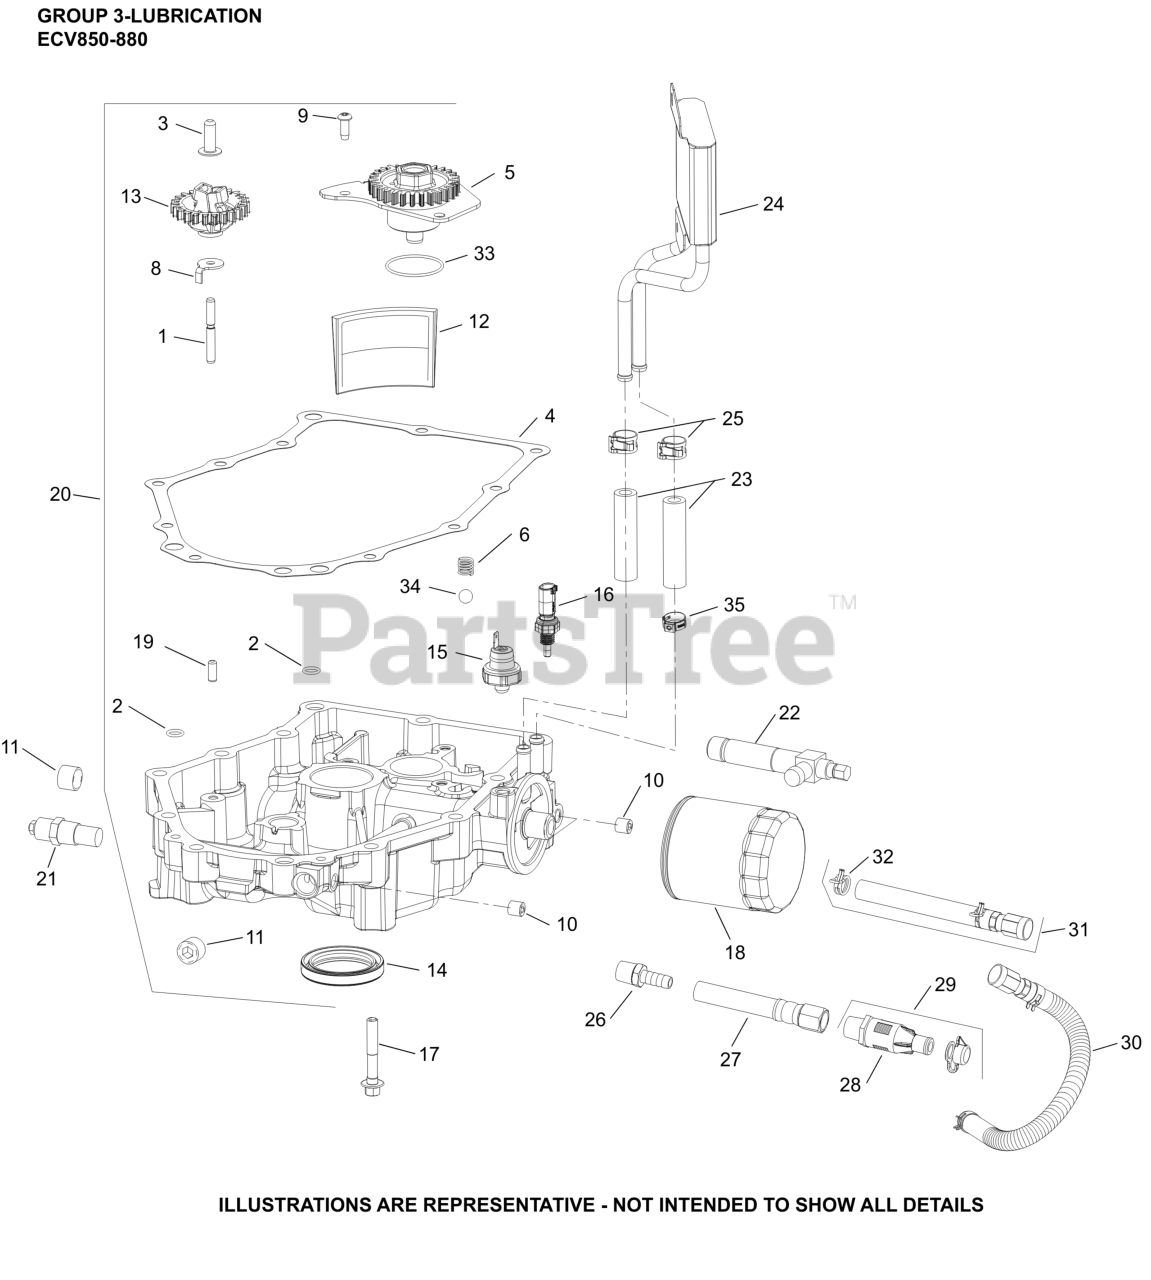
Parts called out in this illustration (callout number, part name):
1	SHAFT, GOVERNOR GEAR
2	O-RING (.5" DIA)
3	PIN, GOVERNOR REGULATING
4	GASKET, OIL PAN
5	PUMP ASSEMBLY, OIL
6	SPRING, COMPRESSION
7	PLUG, CUP
8	TAB, LOCKING
9	SCREW, BUTTON HEAD
10	PLUG, CTSK PIPE 1/8"
11	PLUG, PIPE CTSK 3/8"
12	SCREEN, OIL
13	KIT, GOVERNOR GEAR
14	SEAL, OIL PTO SIDE, BROWN
15	SENSOR, OIL PSI
16	SENSOR, TEMPERATURE
17	SCREW, HEX FLANGE
18	OIL FILTER
20	KIT, OIL PAN (EGOV - W/OIL COOLER)
20	KIT, OIL PAN (MECH GOV W/OIL COOLER)
23	HOSE, OIL COOLER
24	COOLER, OIL
33	O-RING (1.78" DIA)
34	PRESSURE RELIEF BALL
35	CLAMP, HOSE OETIKER
